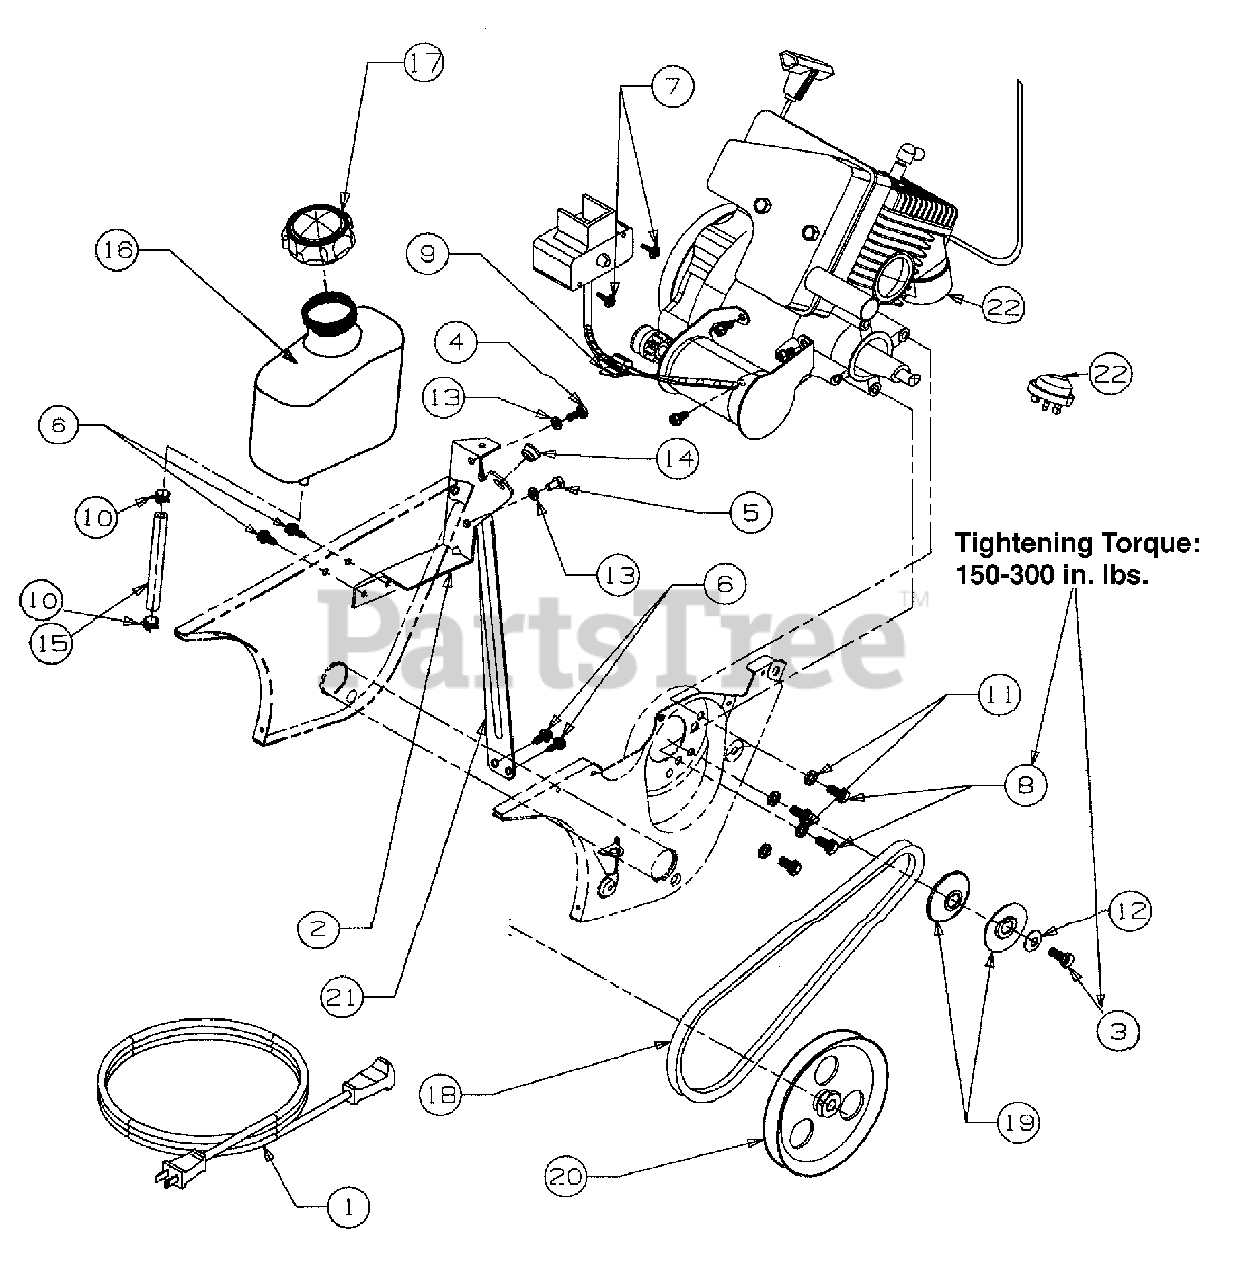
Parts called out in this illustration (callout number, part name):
1	Cord - Extension 110V3M 2 Prong
2	Bracket - Support Fuel Tank
3	Screw - Hex Cap
5	Screw - Hex
6	Screw - Washer
7	Screw - Hex
8	Screw - Hex Cap
9	Clamp - Mounting
10	Clamp - Hose
11	Washer - Lock
12	Washer - Bell
13	Washer - Lock
14	Bushing - Plastic
15	Hose - Fuel Line 16"
16	Tank - Fuel 2 Qt.
17	Cap - Fuel
18	V-Belt
19	V-Pulley Half
20	Pulley
22	Obtain from Engine Manufacturer
